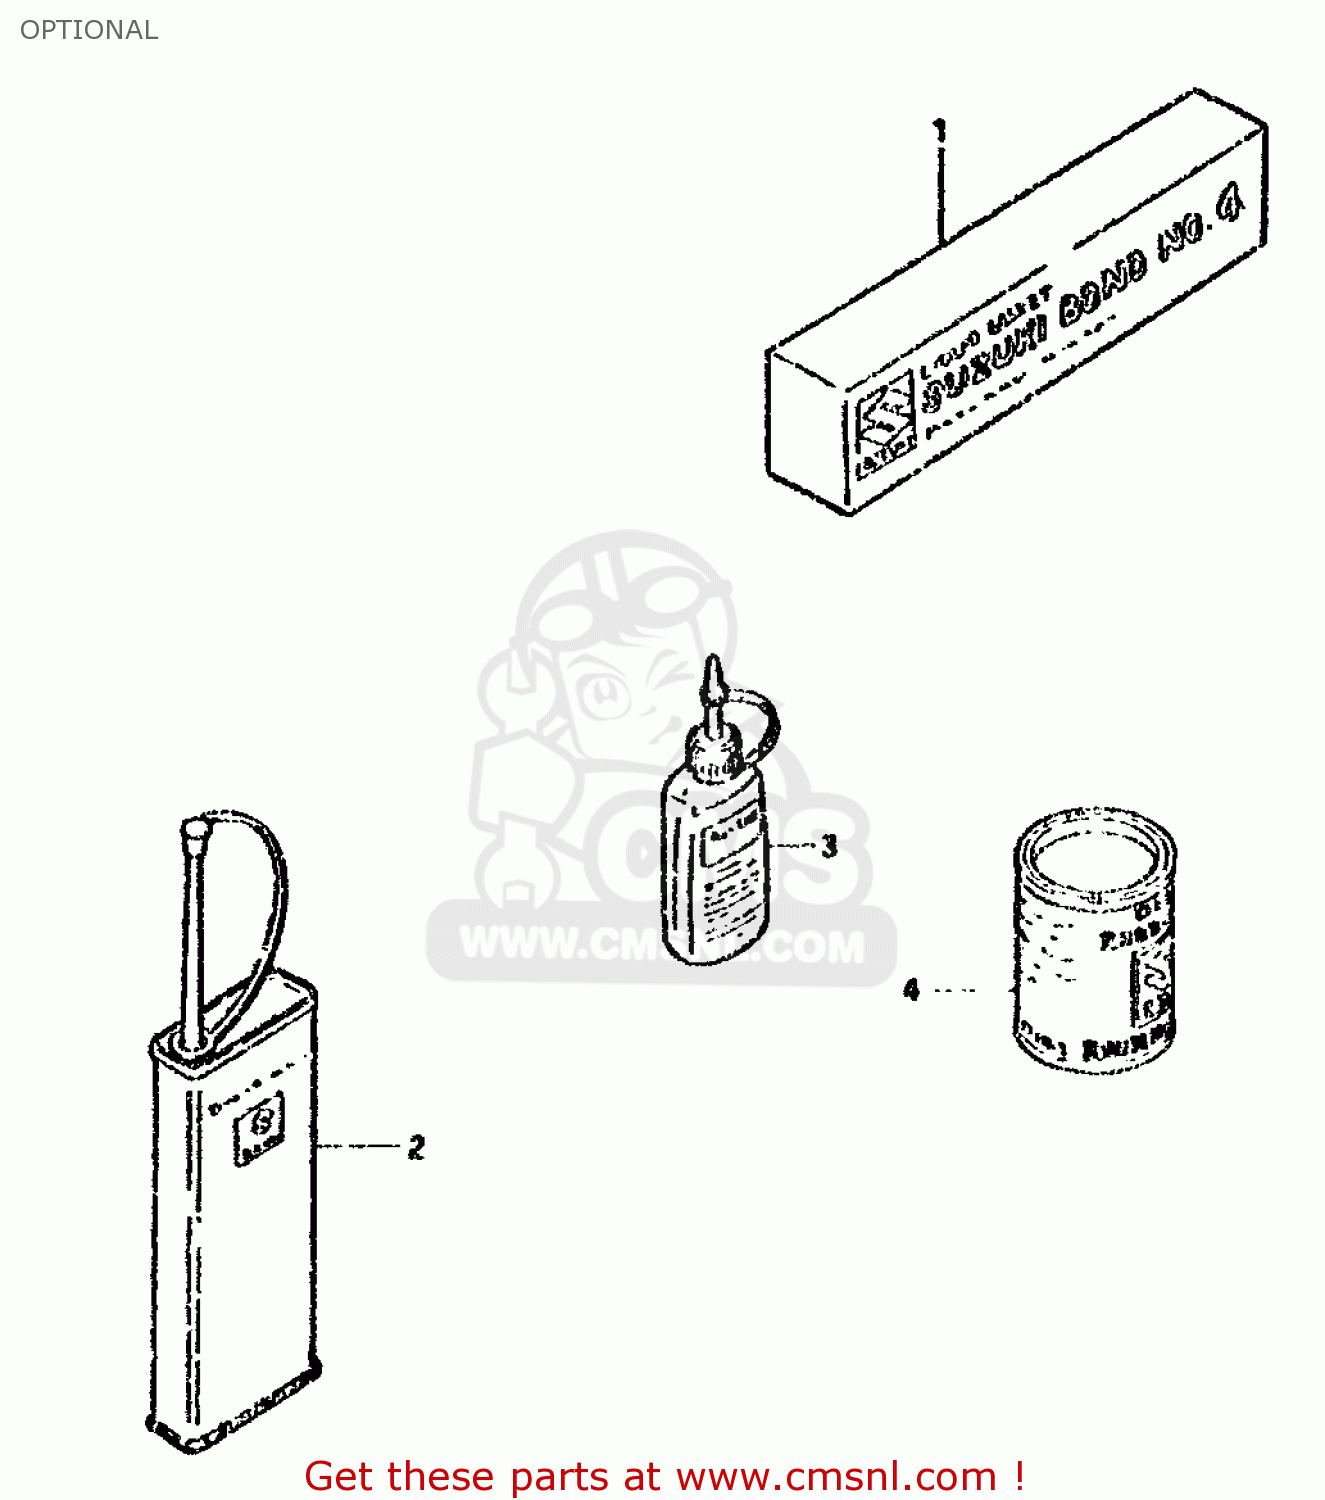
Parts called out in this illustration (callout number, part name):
1	BOND 1104
2	THREAD LOCK NO.1401 CLEAR 200G
3	** SUPERSEEDED
4	GREASE(C)EP2 LITHIUM 150G
